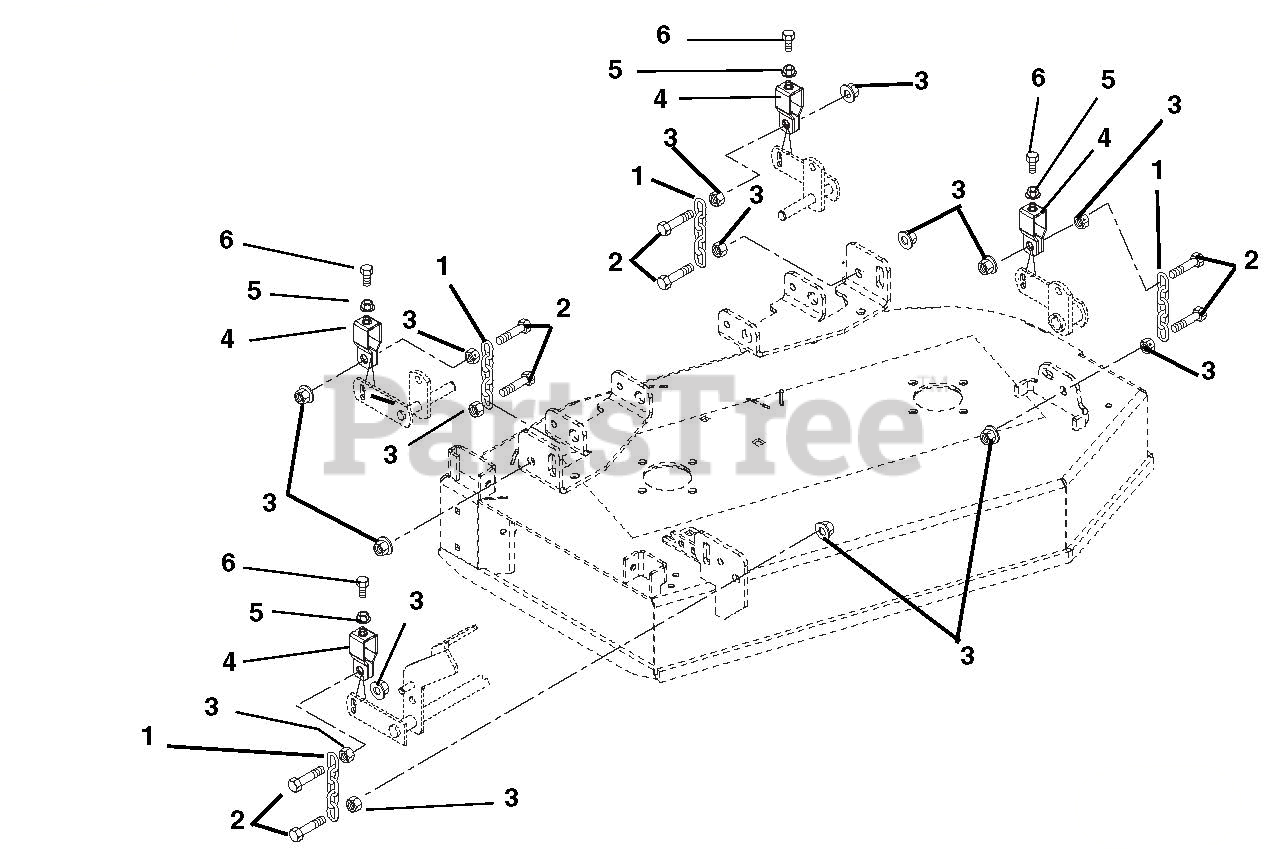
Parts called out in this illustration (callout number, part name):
1	Chain, Link
2	Bolt, Hex M12-1.75 x 50 CLS8.8
3	Nut, Spin Lock-Flange M12-1.75
4	Bracket, Deck Leveling
5	Nut, Jam .312-18
6	Bolt, Hex .312-18 x 2.00 Full Thread Grade 5
